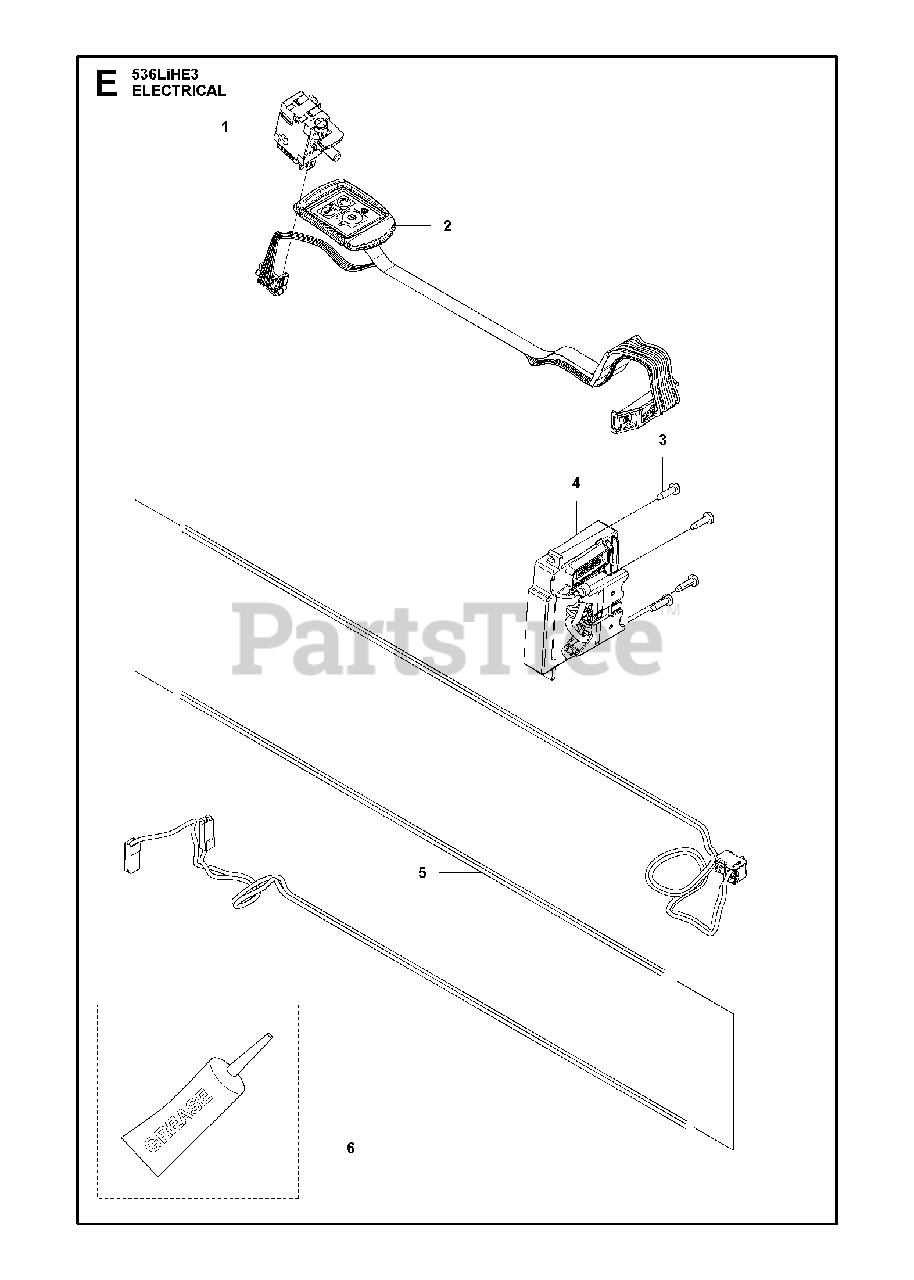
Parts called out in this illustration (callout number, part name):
1	TRIGGER SWITCH
4	CONTROL UNIT BLDC - 536LIHE3
5	WIRING ASSY POLE HEDGE MOTOR B
6	GREASE TUBE Q8 RUYSDAEL WR2
